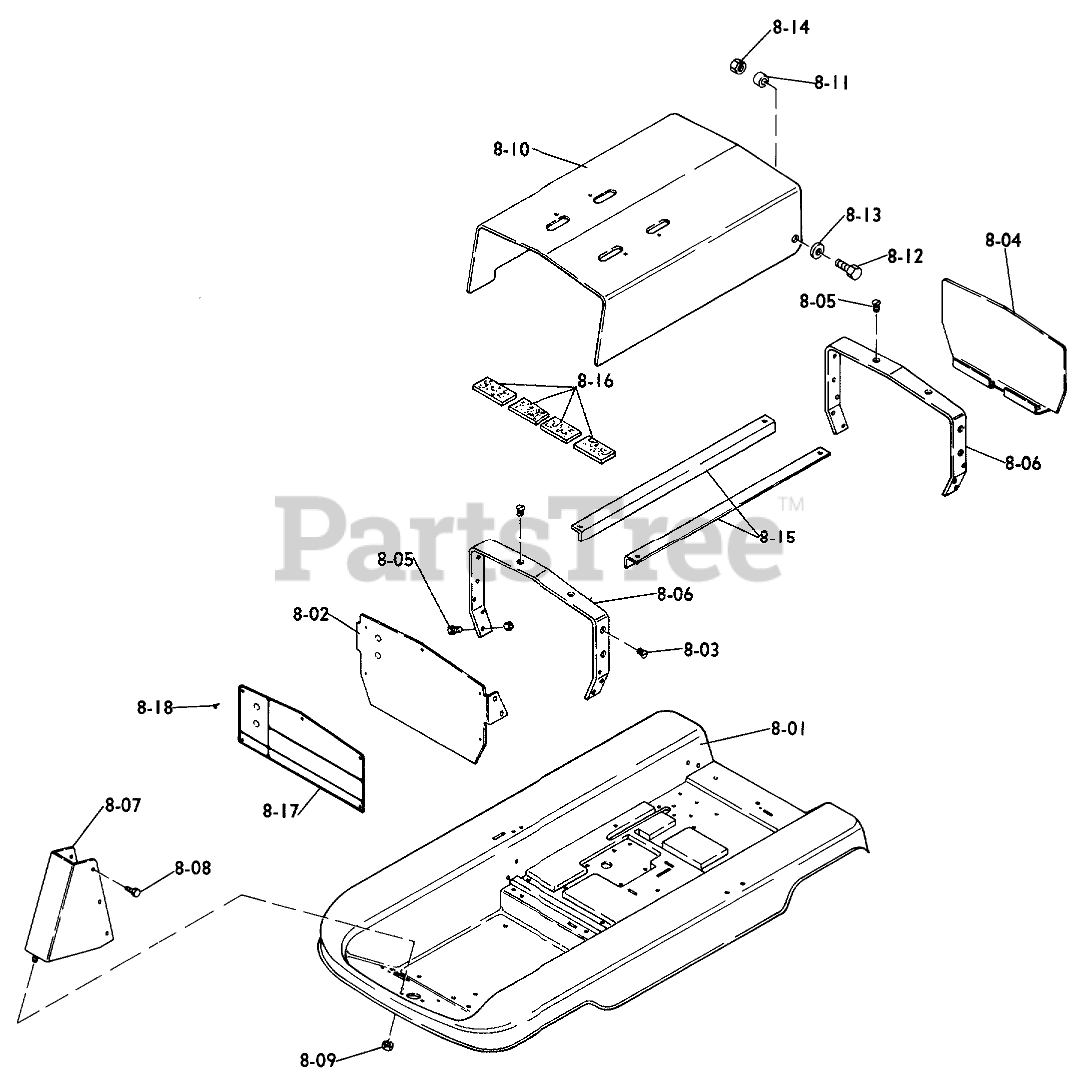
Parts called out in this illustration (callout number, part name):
8-02	Front. Panel
8-03	Screw, Flat Hd. 1/4-20 x 3/4 Swage Form
8-04	Hitch Pin
8-05	SCREW
8-07	Shroud
8-08	Screw
8-09	Nut
8-11	Bushing
8-12	Bolt
8-13	WASHER 5/16 SAE
8-14	Nut
8-15	Seat Support Angle
8-17	Instruction Plate
8-18	Plate Screws
